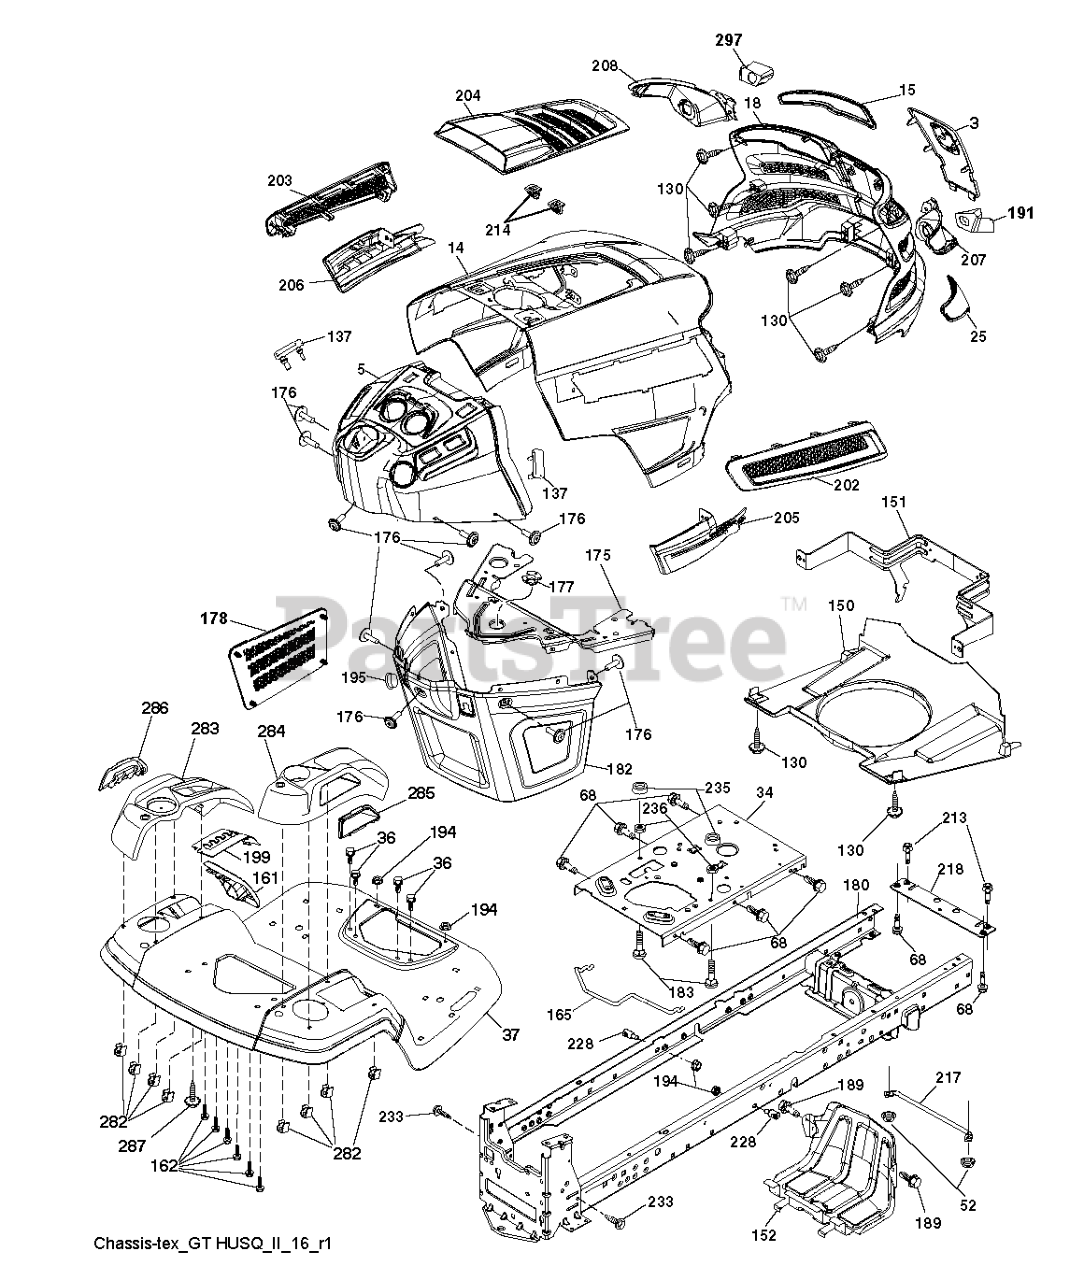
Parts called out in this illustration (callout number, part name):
3	APPLIQUE.SUBASM.GT.HUSQ.II
5	DASH.UPR.ASSY.GT2.SRVMNDER.PTO
14	HOOD.ASM.HUSQVARNA.GT.TEX.ORAN
15	LENS.HEADLIGHT.LH.GTII.2011
18	GRILLE.SUBSTRATE.2011.
25	LENS.HEADLIGHT.RH.GTII.2011
34	PLATE.ENGINE.WELDED.CHASSIS
36	SCREW 5/16"
37	FENDER.TLT.FS.W/CPH/FW/RSF.668
52	LOCKNUT
68	Screw 5/16-18 x 1/2 Hex, Self Tapping 5/16-18 x 1/2
130	SCREW.#10 X 0.750.BOS
137	BUMPER DASH
150	AIR.DUCT.GTV.BLACK
151	BRACKET.PIVOT.HOOD.GT.HUSQ.II
152	SHIELD.BROWNING.W/TEX
161	WINDOW.FUEL.LT.HUSQ.TEX.498
162	SCREW.HI-LO.CONSOLE
165	SUPPORT.TANK.REAR.W/TEX
175	PLATE.CROSSMEMBER.HUSQ
176	SCREW.#10-24X5/8.RN.QU
177	BUSHING, STEERING
178	CARGO.ASM.NET.TXGT.W/C
180	CHASSIS
182	DASH.LOWER.COMMON.12V.ADAPTOR
183	BOLT.5/16-18X1-1/4 FULL THD
189	SCREW
191	INSERT.REFLECTIVE.RH.HUSQ.GTII
194	NUT LOCK HEX FLANGE 5/16-18
195	PLUG.HOLE.DASH.LOWER.12V.BLK
199	PLATE.DECK.LIFT.HUSQ.LT
202	VENT.SIDE.RH.GT.HUSQ.II.
203	VENT.SIDE.LH.GT.HUSQ.II.498
204	VENT.TOP.HUSQ.GT2
205	SIDE.TRIM.RH.GT.HUSQ.II
206	SIDE.TRIM.LH.GT.HUSQ.II.GRAY
207	BEZEL LIGHT.RH.GT.II.MYLAR
208	BEZEL LIGHT.LH.GT.II.MYLAR
213	BOLT
214	CLIP.RETAINER.TINNER.
217	ROD.PIVOT.HOOD
218	X-PIECE.HOOD.STOP.NON/
228	STUD.FASTNER.W/ANTI-ROTATE
233	BOLT.SHOULDER
235	SPACER FENDER
236	NUT.CENTERLOCK.5/16-
282	CLIP.RETAINER.CONSOLE.LT.HUSQ
283	CONSOLE.ASM.LFT.RSF.HUSQ.LT
284	CONSOLE.SHFT.PDL.CNTRL.HUSQ.LT
285	CONSOLE INSERT RH
286	CONSOLE.INSRT.LH.HUSQ.LT.BLACK
287	SCREW 1/4X20
297	INSERT.REFLECTIVE.LH.HUSQ.GTII
